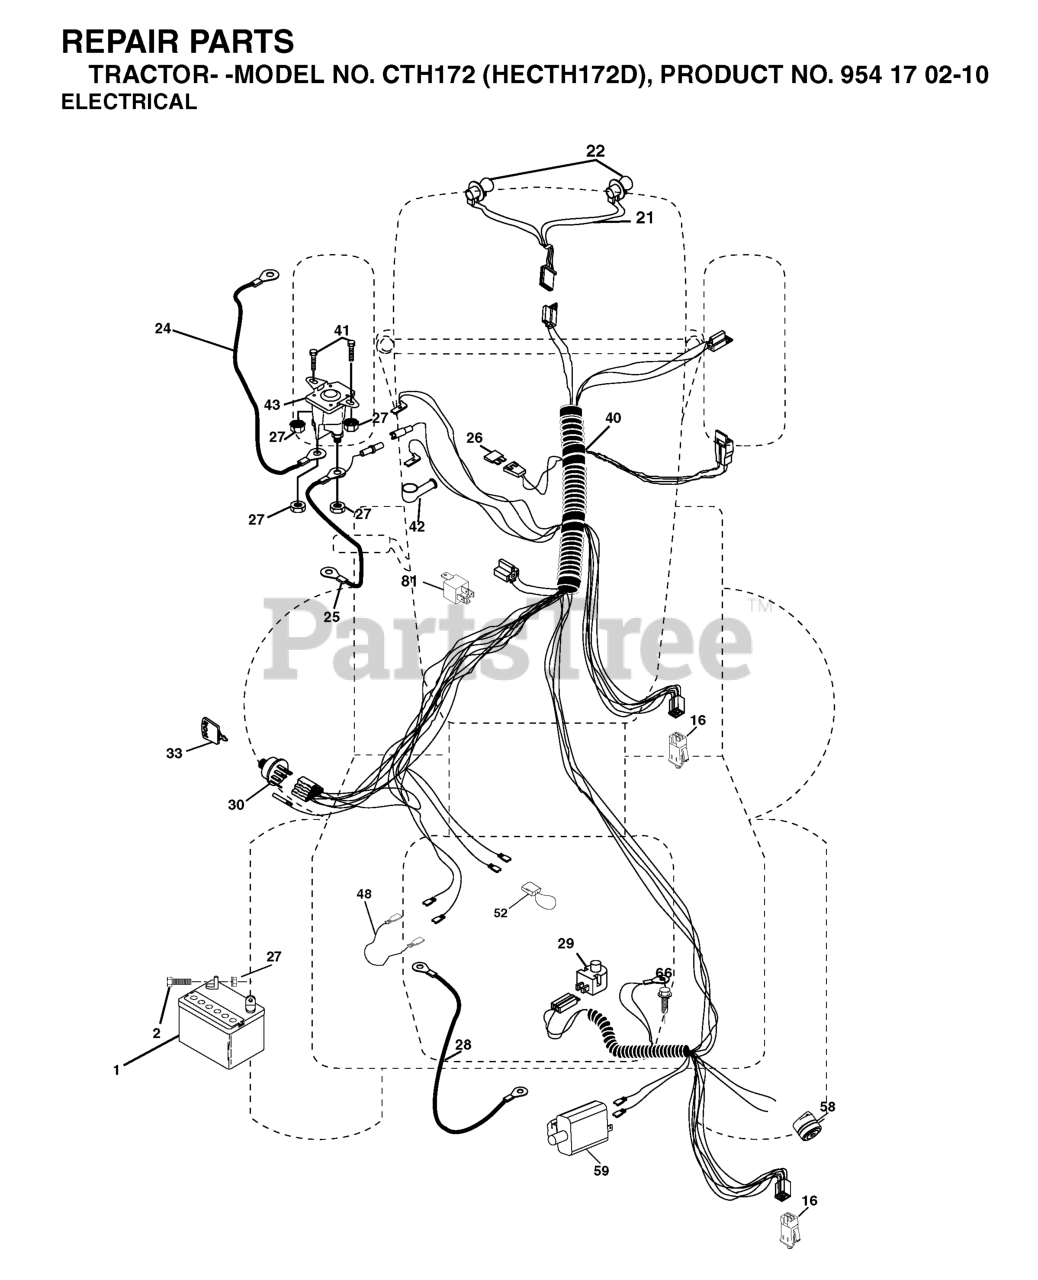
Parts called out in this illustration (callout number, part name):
1	BATTERY 12V .35 AMP
2	BOLT.HEX.1/4.X.3/4.DICHROMATE
16	SWITCH INTERLOOK PUSH-IN
21	HARNESS.W/LIGHT SOCKET
24	BATTERY CABLE GT
25	CABLE BATTERY
26	FUSE 20AMP
27	NUT
28	CABLE GROUND
29	RP.SWITCH.PLUNGER.NC.GRAY
30	IGNITION SWITCH
33	KEY MLD GEN DELTA
41	BOLT
42	TERMINAL COVER
43	SOLENOID
48	ADAPTER.AMMETER
52	WIRE PROTECTION LOOP
58	BUZZER
59	.WITCH.FULL BAGGER.INDICATOR
81	RELAY.ASSY.T
